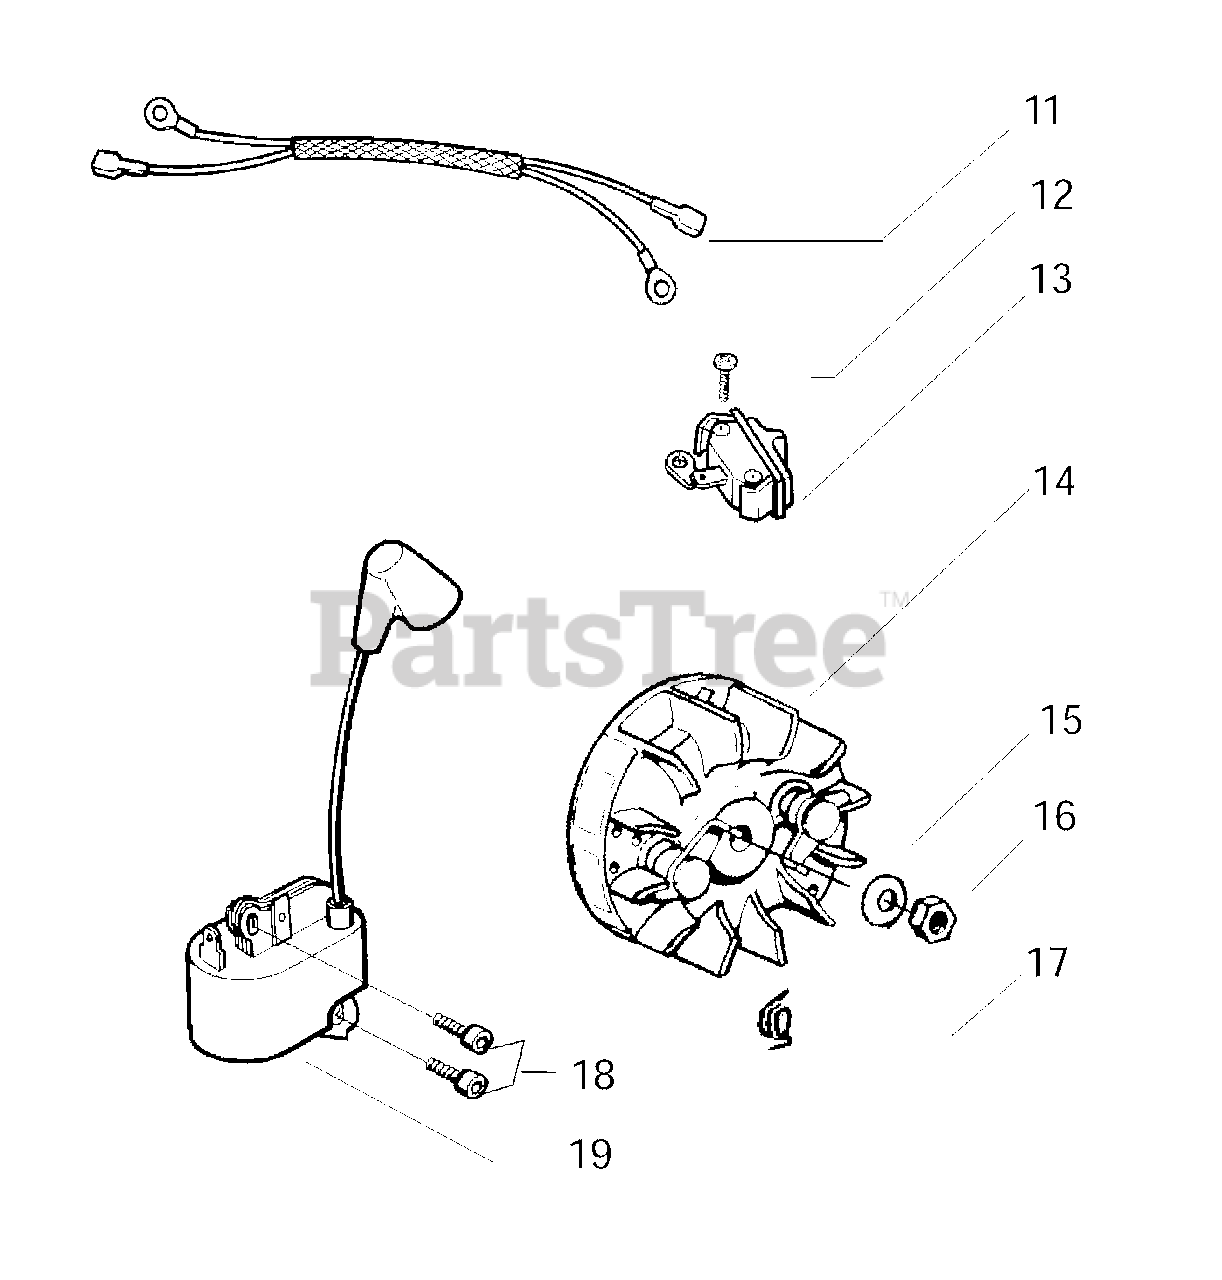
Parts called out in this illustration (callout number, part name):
11	Leadwire Harness Ass'y.
13	Ignition Switch
14	Assy. Flywheel
15	Flywheel Washer
17	Spring - Starter Dog
19	Module - Ignition
